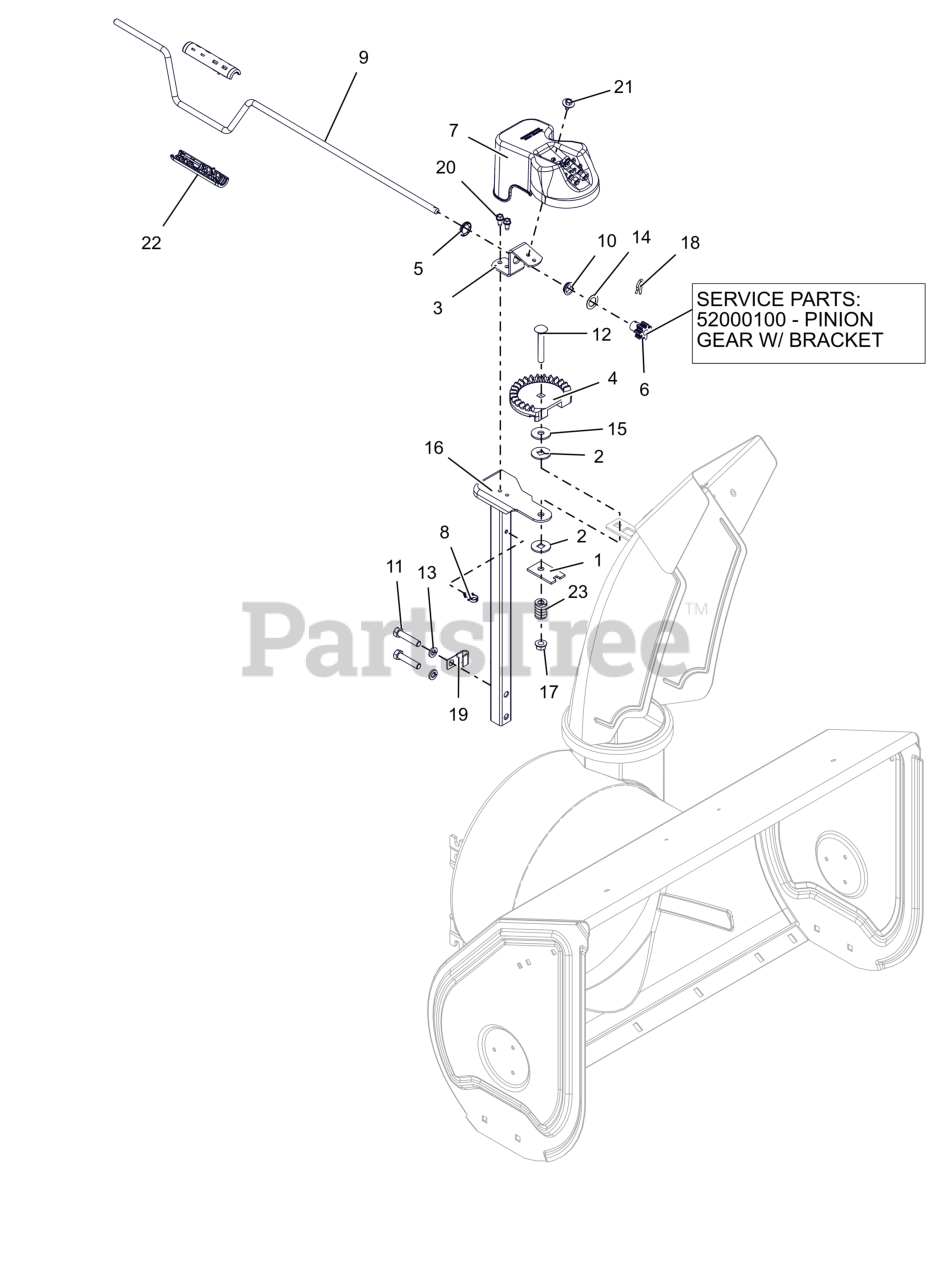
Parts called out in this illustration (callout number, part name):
1	PLATE, FRICTION
2	FRICTION WASHER
3	BRACKET, PINION GEAR
4	CHUTE GEAR
5	PUSHNUT .625
6	PINION GEAR - CHUTE
7	GEAR COVER ASSY LG SHEAR BOLT
8	CLIP, CABLE GUIDE
9	ROD, CHUTE CRANK
10	BUSHING, POLYLINER-.63 SNAPIN
11	BLT, HEX .38-16X1.75 G5 ZCC
12	BLT,RHSN .38-16X2.50 G5 ZCC
13	WSHR,LK-REG .375X.094 ZCC
14	WSHR-THRST .625 X 1.0 X .03
15	WSHR FL STL .406X1.25X.10ZC120
16	PEDESTAL, CHUTE - CRANK
17	NUT-LK-CTR-FLG .375-16 GF ZCC
18	PIN, SPRING CLIP
19	J-CLAMP
20	SCR-TAP .25-20X.50 HWH ZCC
21	SCR, TAP .25-20X.50 LG HWH ZCC
22	KNOB,CHUTE CRANK-DELUXE
23	SG-COMP .187X.56X1.62
